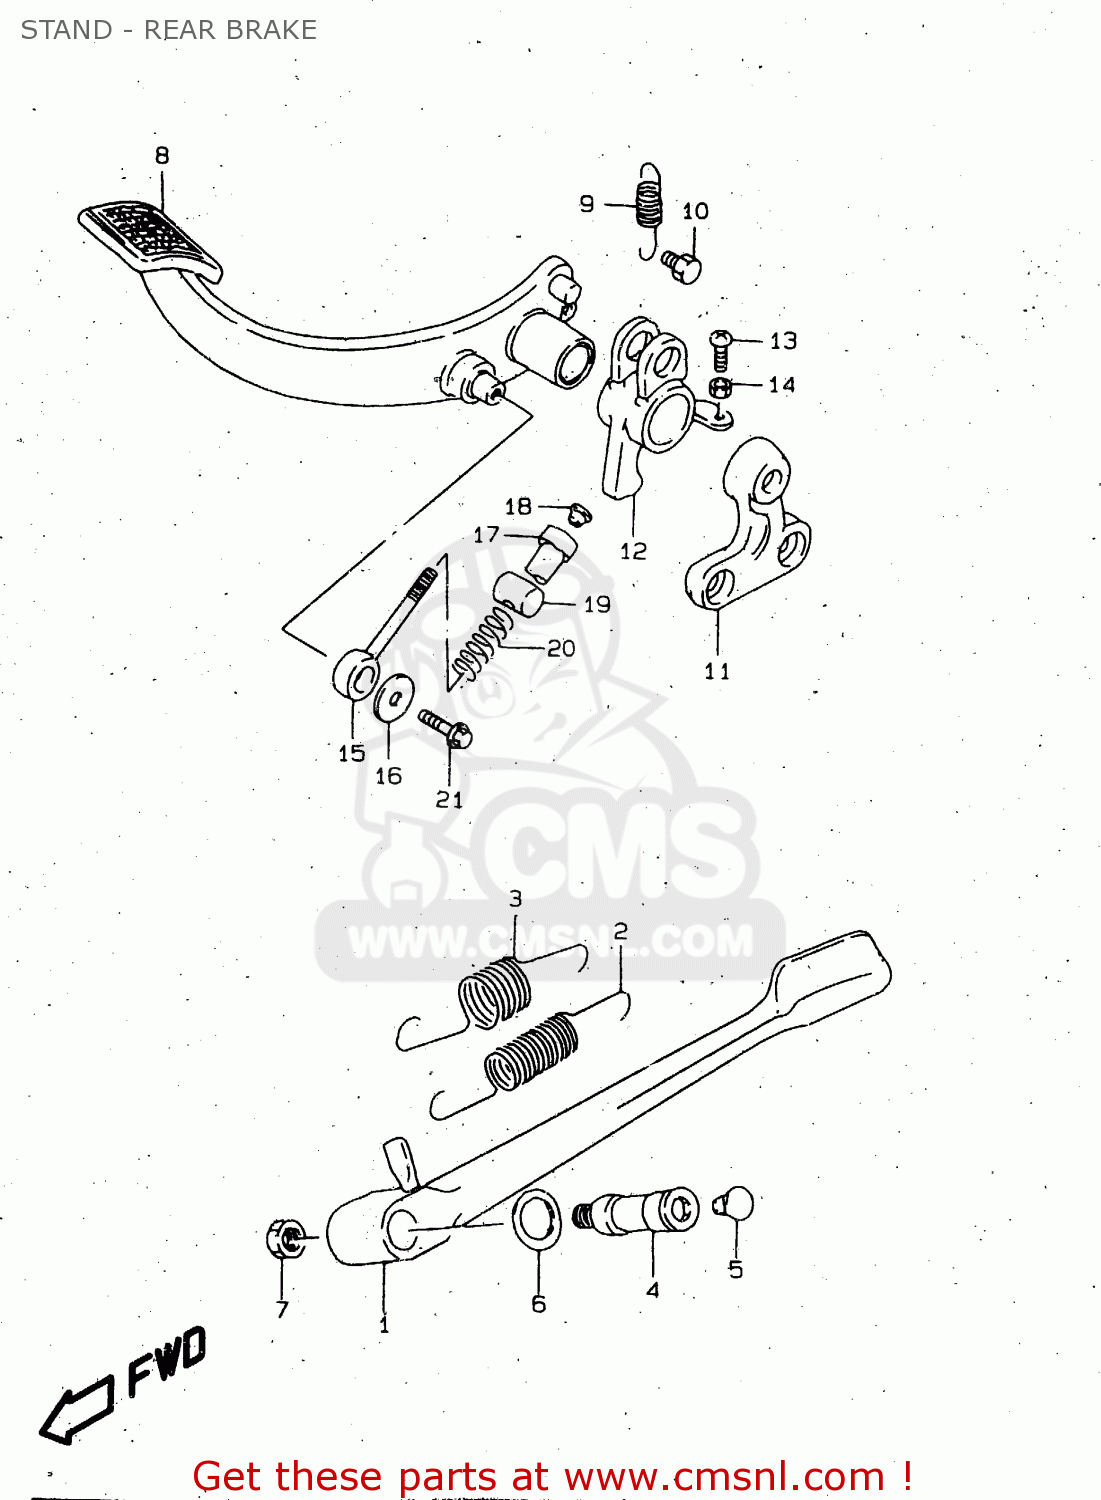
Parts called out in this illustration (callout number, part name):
1	STAND,PROP
2	SPRING
3	SPRING
4	BOLT,PROP STAND
5	CAP(OD:12)
6	THRUST WASHER
7	NUT
8	PEDAL ASSY,BRAKE
9	SPRING
10	SCREW(6X10)
11	BRACKET,BRAKE PEDAL BOSS
12	ARM,RR BRAKE
13	SCREW(5X14)
14	NUT
15	LINK,BRAKE PEDAL
16	WASHER(6.5X18X1.5)
17	NUT,BRAKE PEDAL LINK
18	CAP(OD:10)
19	PIN
20	SPRING
21	BOLT
